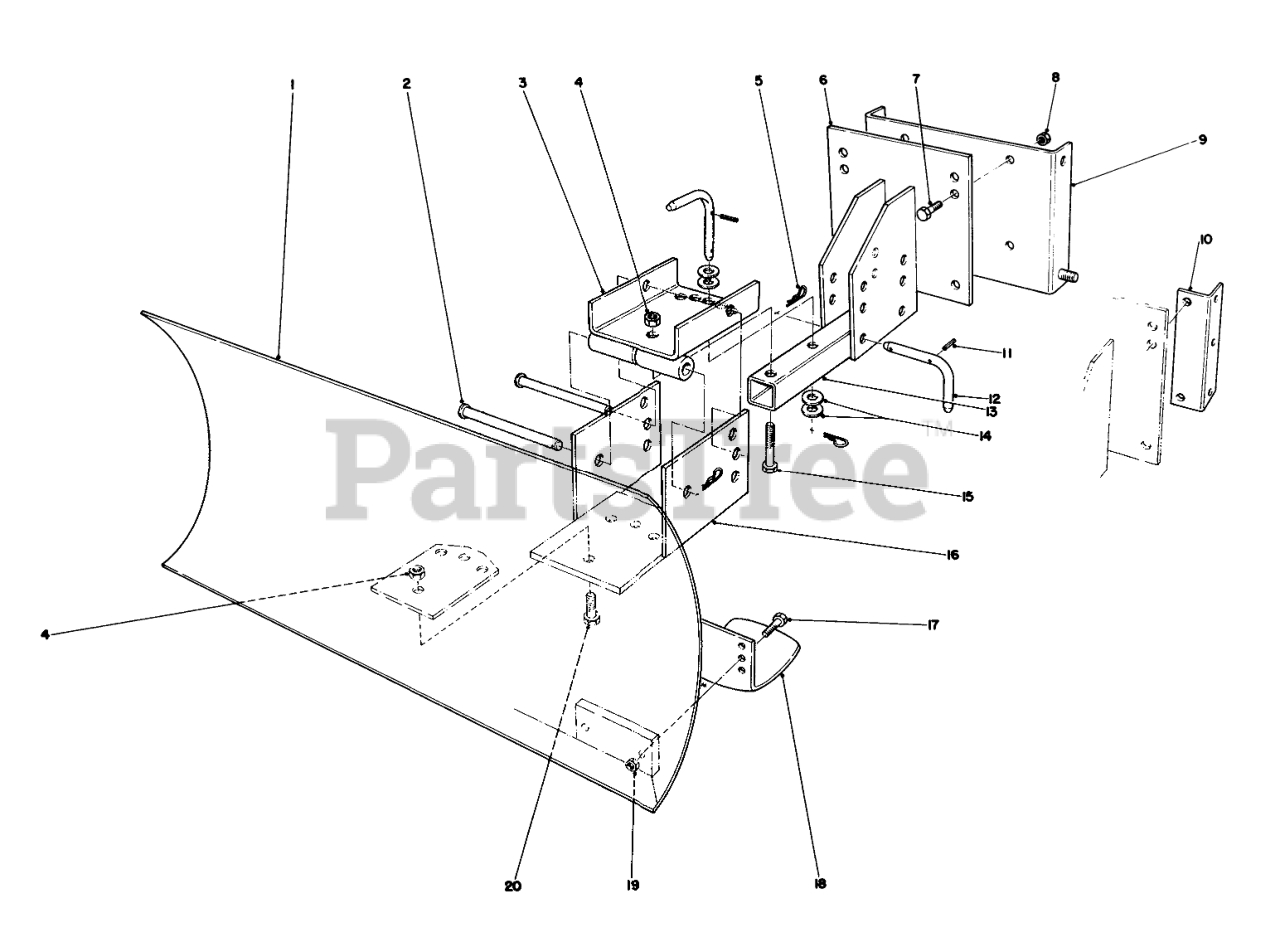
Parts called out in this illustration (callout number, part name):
1	Blade
2	PIN-CLEVIS
3	Swivel Bracket
4	1/2-13 CONELOCK NUT
5	PIN-HAIR
6	Mounting Plate
7	SCREW-HH
8	NUT-LOCK, CONE
9	Mounting Plate (Used with 826 & 1132 Units only)
10	Mounting Rail (used with 421 units only)
11	PIN-SPRING
12	Pivot Pin (Incl. Ref. #11)
13	Blade Tongue
14	WASHER-FLAT
15	SCREW-HH
16	Blade Adjustment
17	SCREW-HH
19	NUT-LOCK, CONE
20	SCREW-HH
